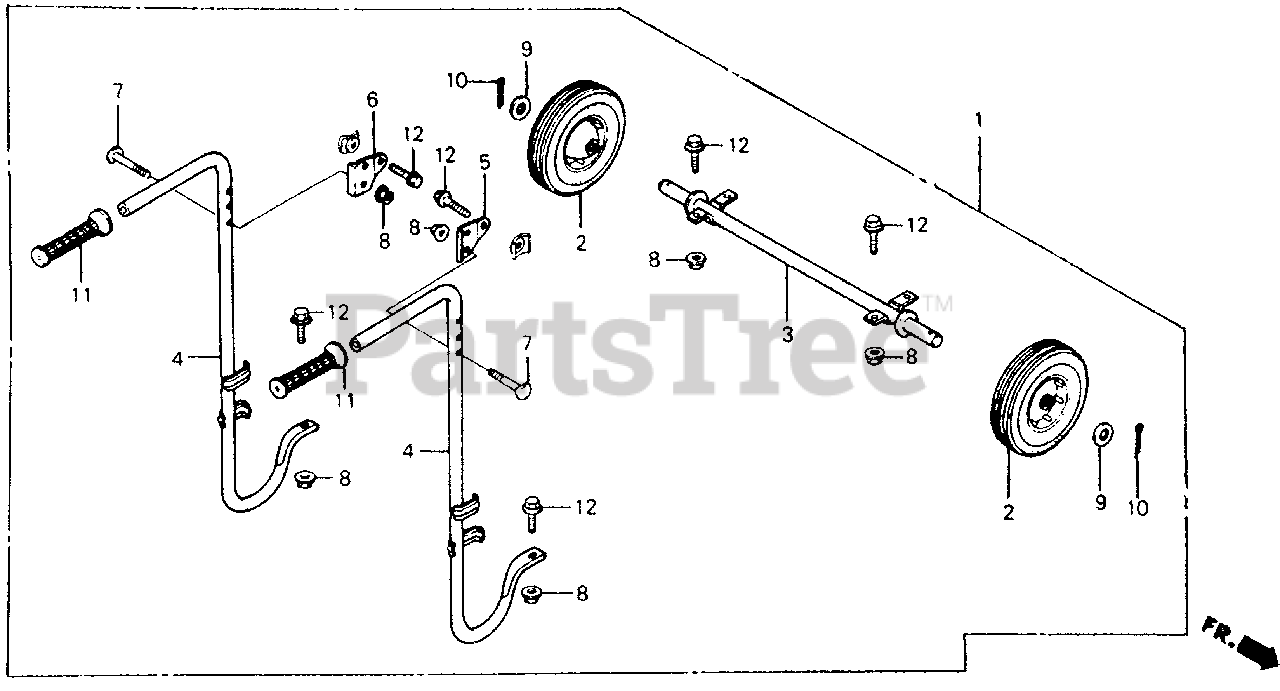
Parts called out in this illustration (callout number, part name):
1	WHEEL KIT (2-WHEELS)
2	WHEEL (10"X2.75")
3	SHAFT, WHEEL
4	HANDLE, CARRY
4	HANDLE, CARRYING
5	HOLDER, R. HANDLE
6	HOLDER, L. HANDLE
7	BOLT, HANDLE HOLDER
8	NUT, FLANGE (8MM)
9	WASHER, FLAT (20MM)
10	PIN, COTTER (4.0X30)
11	GRIP, R. HANDLEBAR
12	BOLT, FLANGE (8X16)
